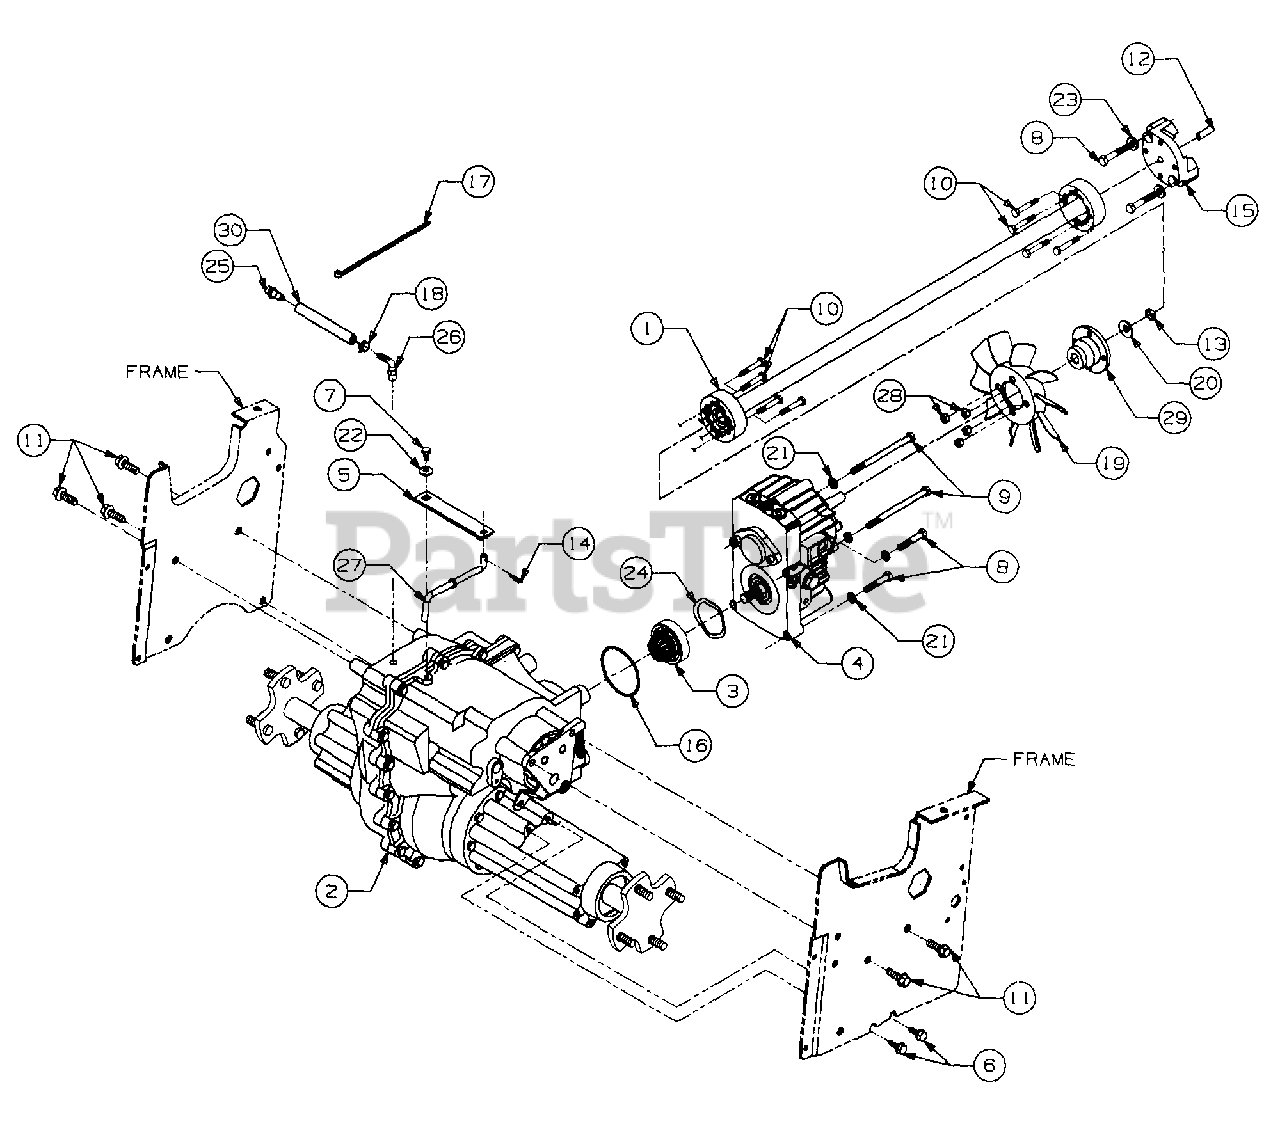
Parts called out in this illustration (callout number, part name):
1	Shaft Assy, Drive, 29.06 Lg
2	Transmission Assembly, Hydro
3	Pinion Assy, Input
4	Pump, Hydrostatic
5	Arm, Hydro Dump
6	Screw, Hex Wash Hd Tap, 5/16-18 x .75
7	Screw, Hex Wsh Hd Tap, 1/4-20 x .75 GR5
8	Screw, Hex Patch, M8-1.25 x 50mm
9	Screw, Hex Cap, 5/16-18 x 4.5 GR5
10	Screw, Hex Patch, 1/4-20 x 1.62 GR5
11	Screw, Hex Wash Hd Tap, 3/8-16 x 1.25
12	Pin, Locating
13	Nut, Hex Center Lock Jam, 3/8-24
14	Pin, Internal Cotter, 5/16 Dia x 1.12
15	Adapter, Drive Shaft
16	O-Ring, 2.75 x .103
17	Tie, Self-Clinch Cable
18	Clamp, Hose
19	Fan, 10 Blade Cooling
20	Washer, Bell, .380 x .88 x .063
21	Washer, Lock, 5/16
22	Washer, Bell, .265 x .75 x .062
23	Washer, Flat, .312 x .750 x .119
24	Washer, Spring Wave, 1.96 x 2.44 x .06
26	Fitting, Elbow
27	Rod, Hydro Disengagement
28	Nut, Fan, 1/4-20
29	Adapter, Pump
30	Line, Fuel, 7 in. Lg
